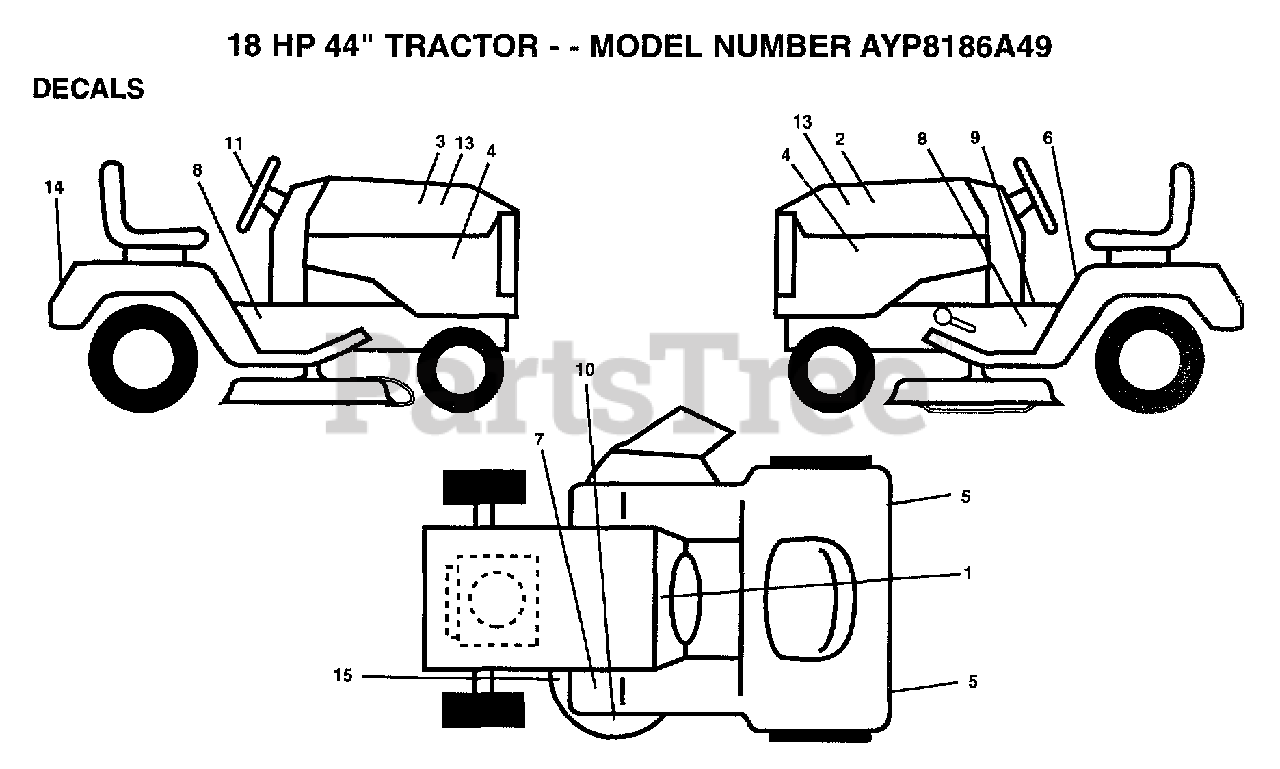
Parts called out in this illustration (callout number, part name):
1	DECAL.DASH.INST.
1	VALVE CAP
2	DECAL HD LH WIZ +
2	VALVE STEM LT
3	DECAL HD RH WIZ +
3	FITTING LT
4	DECAL PANEL SIDE
5	REFLECTOR-TAIL YT
5	TUBE.5.3/4.5/6
5	TUBE.23X8/10-12
6	DECAL
6	"RIM ASM 8"" FRT"
6	"RIM ASM 12"" REAR"
7	HUB CAP
8	DECAL CHASSIS
8	"FLANGE, BEARING"
9	DECAL BRAK PARK
9	WASHER
10	DECAL DECK WIZ +
11	DECAL STEER WHL
15	"DECAL.V.BELT.44"""
